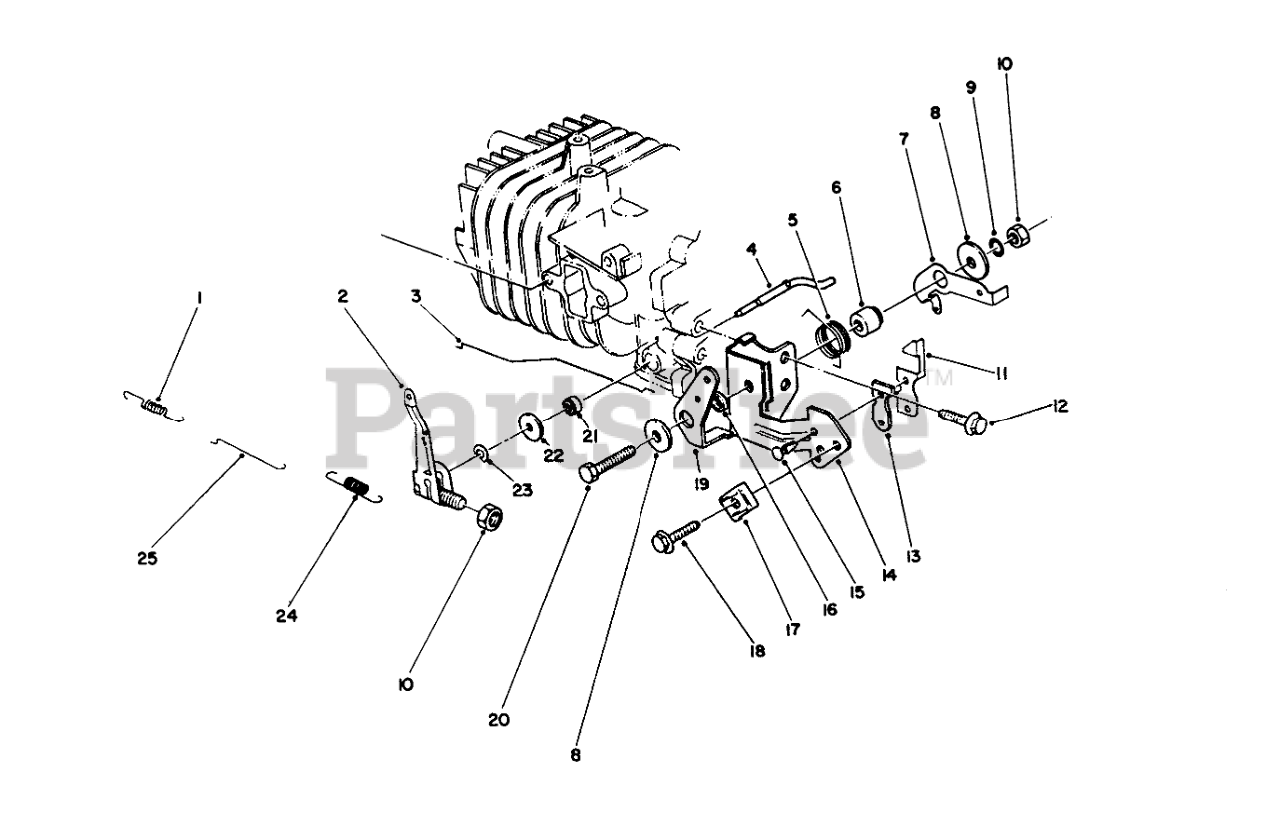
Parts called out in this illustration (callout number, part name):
1	SPRING
2	ARM-GOVERNOR
3	ROD-CHOKE
4	Shaft-Govemor
5	SPRING-CHOKE LEVER
6	Gov Lever Spacer
7	LEVER-SPRING, GOVERNOR
8	WASHER
9	LOCKWASHER
11	TERMINAL-KILL SWITCH
13	INSULATOR-KILL SWITCH
14	BRACKET-THROTTLE, CONTROL
15	KILL SWITCH RIVET
16	SPACER-CHOKE LEVER
17	CLAMP
19	LEVER-CONTROL, CHOKE
21	SEAL-OIL
22	WASHER
23	E-RING
24	SPRING-GOVERNOR
25	ROD-CARBURETOR
